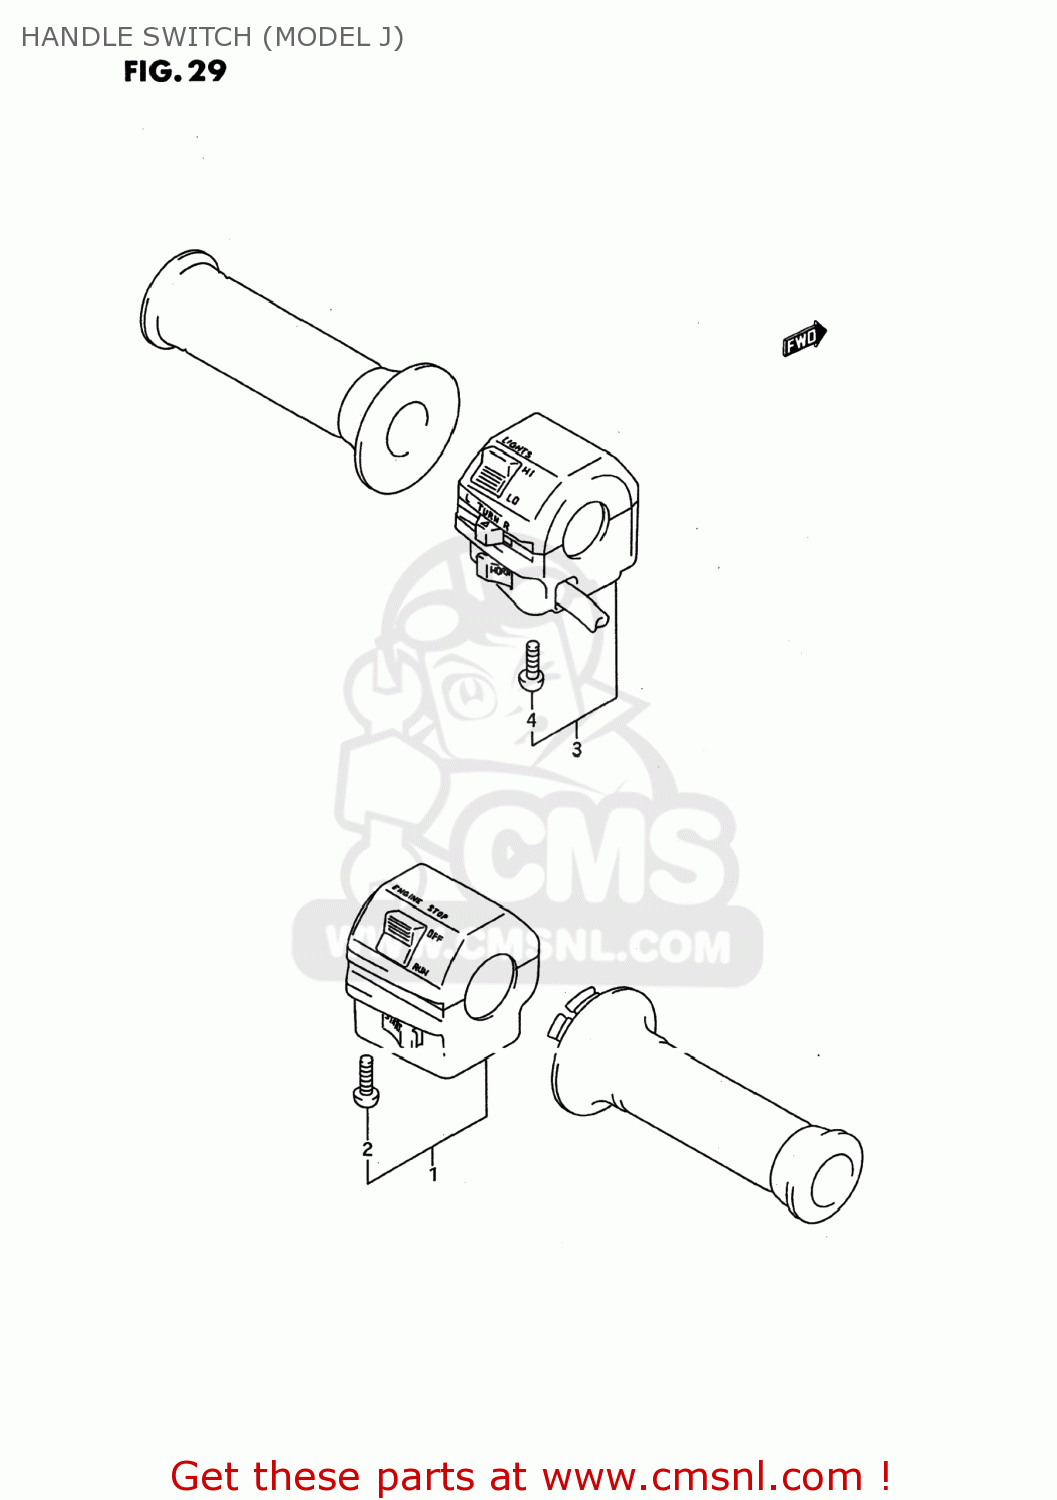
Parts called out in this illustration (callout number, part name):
1	SWITCH ASSEMBLY,HANDLE,RIGHT
2	SCREW, 5X45
3	SWITCH ASSEMBLY,HANDLE,LEFT
4	SCREW, 5X45
